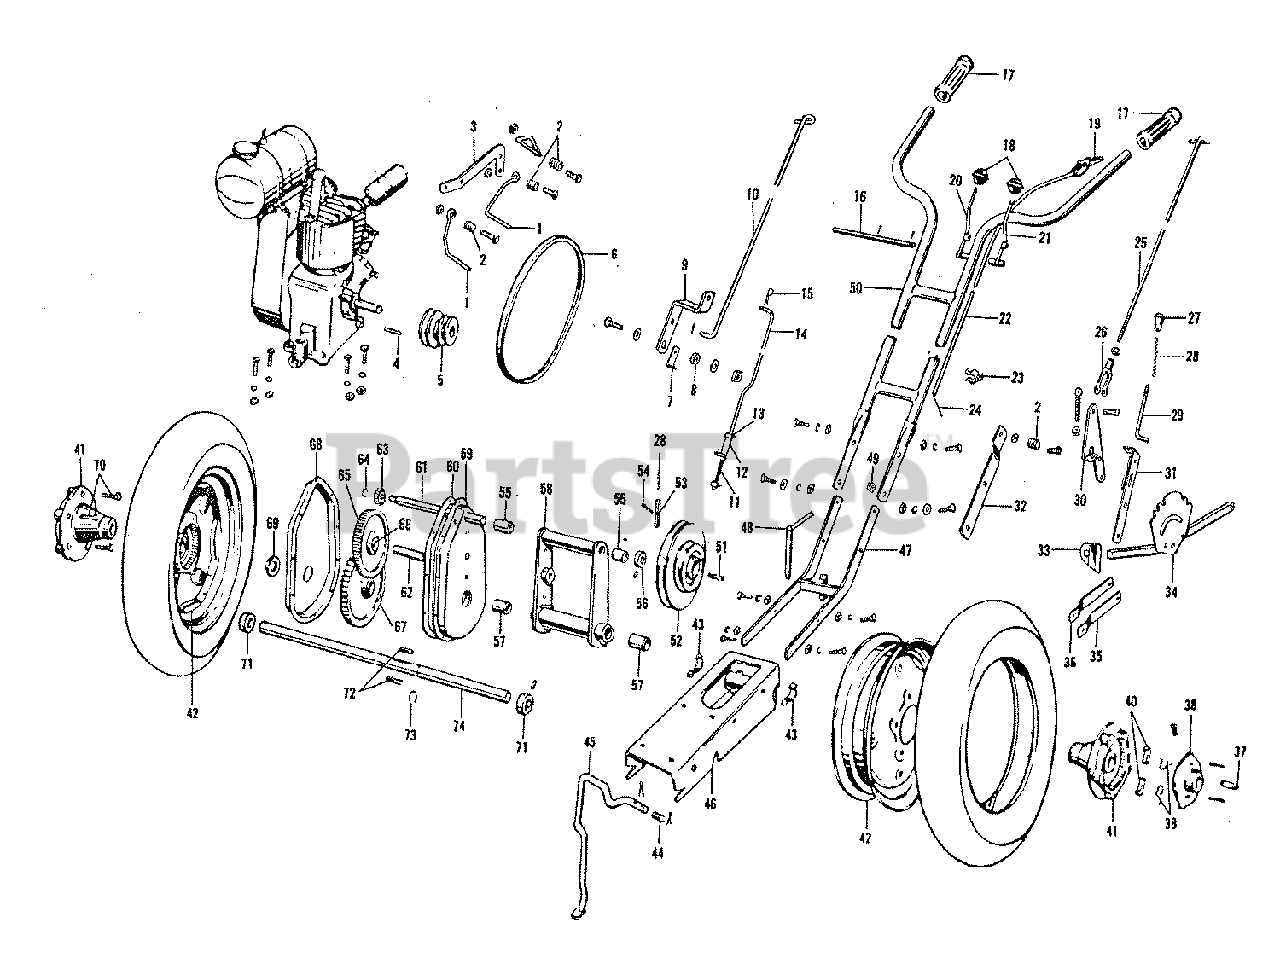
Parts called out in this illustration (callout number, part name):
1	BELT STOP
3	BELT STOP HOLDER
4	ENGINE PULLEY KEY
5	ENGINE PULLEY
6	BELT, 43" O. CIR. V-Type
7	STOP, Lever
9	LEVER, Lower Clutch
10	ROD, Upper Idler
12	ROD SOCKET ASSEMBLY
14	ROD, Lower Idler
15	CLIP, Spring
16	SHAFT, Lever
17	RUBBER GRIP
18	CLUTCH LEVER BALL
19	THROTTLE CONTROL LEVER ASSEMBLY
20	R. CLUTCH LEVER ASSEMBLY
21	L. CLUTCH LEVER ASSEMBLY
22	THROTTLE CABLE
23	CABLE CLIP
24	WIRE, Throttle
25	ROD, Clutch
27	KNOB, Plunger
28	TRANSMISSION PULLEY AND PLUNGER SPRING
30	LEVER, Lower Clutch
31	SHIFT LEVER ASSEMBLY
32	FRAME EXTENSION
33	GUIDE, Shaft
34	THROW-OUT ASSEMBLY
35	THROW-OUT LINK
36	TAPPED THRO-OUT LINK
37	KEY, For Ratchet Cage
38	CAGE, Ratchet
39	SPRING, Ratchet
40	DOG, Ratchet
41	HUB, Wheel
42	DRIVE WHEEL 4" RIM
43	CLAMP, Bearing
44	SPRING, Stand
45	STAND ASSEMBLY
46	BASE ASSEMBLY
47	FRAME ASSEMBLY
48	HITCH PIN ASSEMBLY
49	CLAMP, Throttle Wire Housing
50	HANDLE ASSEMBLY
51	KEY, Transmission Pulley
52	TRANSMISSION PULLEY
53	PIN, Transmission Pulley
54	SPRING PIN, Transmission Pulley
55	BUSHING FOR PULLEY SHAFT, 3/8 x 3/4 x 1-7/16"
56	SET COLLAR (Pulley Shaft)
57	SHAFT, Bushing For Transmission, 1 x 1 1/8 x 2"
58	BEARING HOUSING ASSEMBLY
59	GEAR CASE
60	GASKET, Gear Case
61	SHAFT, Pulley
62	SPINDLE, Intermediate
63	PINION, Reduction
64	RETAINING RING FOR PULLEY SHAFT
65	CLUSTER GEAR ASSEMBLY
66	BUSHING, Intermediate, 5/8 x 3/4 x -7/16"
67	GEAR, Drive
68	GEAR CASE COVER
69	GROMMET #931-16-20
71	SET COLLAR (Axle)
72	AXLE KEY, 3/4 x 1/4 x 1 1/8"
73	RETAINING RING FOR AXLE
